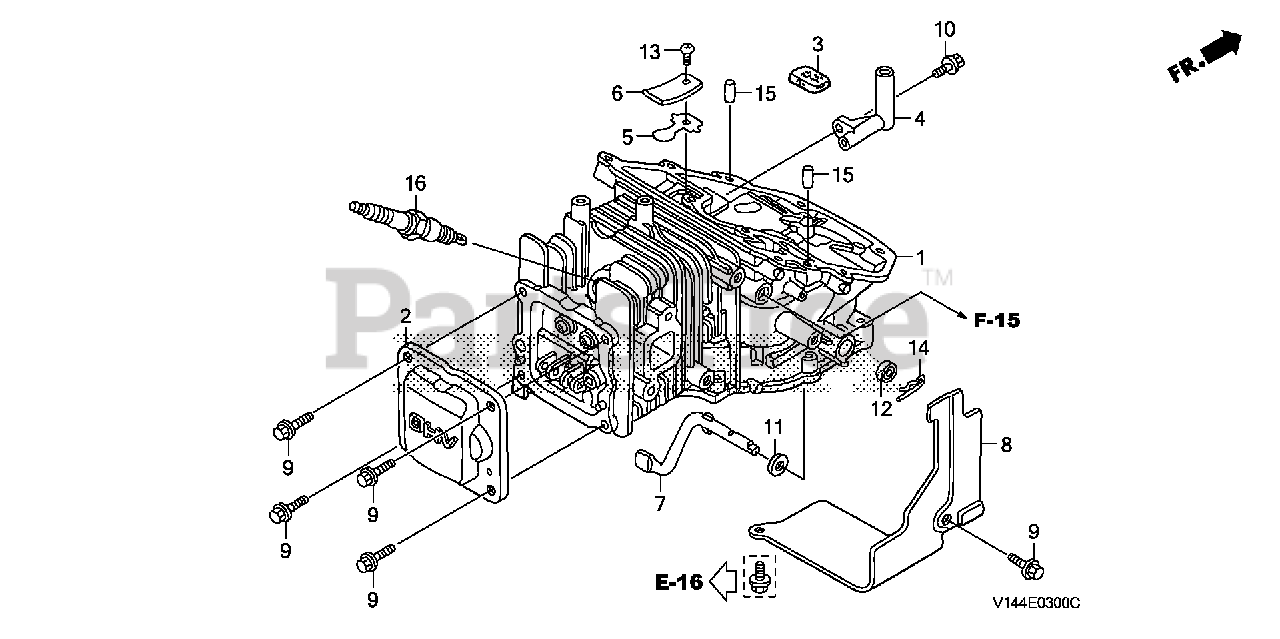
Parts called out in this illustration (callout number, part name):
2	COVER, HEAD
3	FILTER, BREATHER
4	PIPE, BREATHER
5	VALVE, OIL OUTLET
6	PLATE, STOPPER
7	SHAFT, GOVERNOR ARM
9	BOLT, FLANGE (5X12)
10	BOLT (4X10)
11	WASHER (5.2X9)
12	OIL SEAL (5X11X5)
13	SCREW, PAN (3X5)
14	PIN, LOCK (6MM)
15	ROLLER (6X14.8)
15	ROLLER (6X15)
16	SPARK PLUG (U14FSR-UB)
16	SPARK PLUG (CR4HSB)
